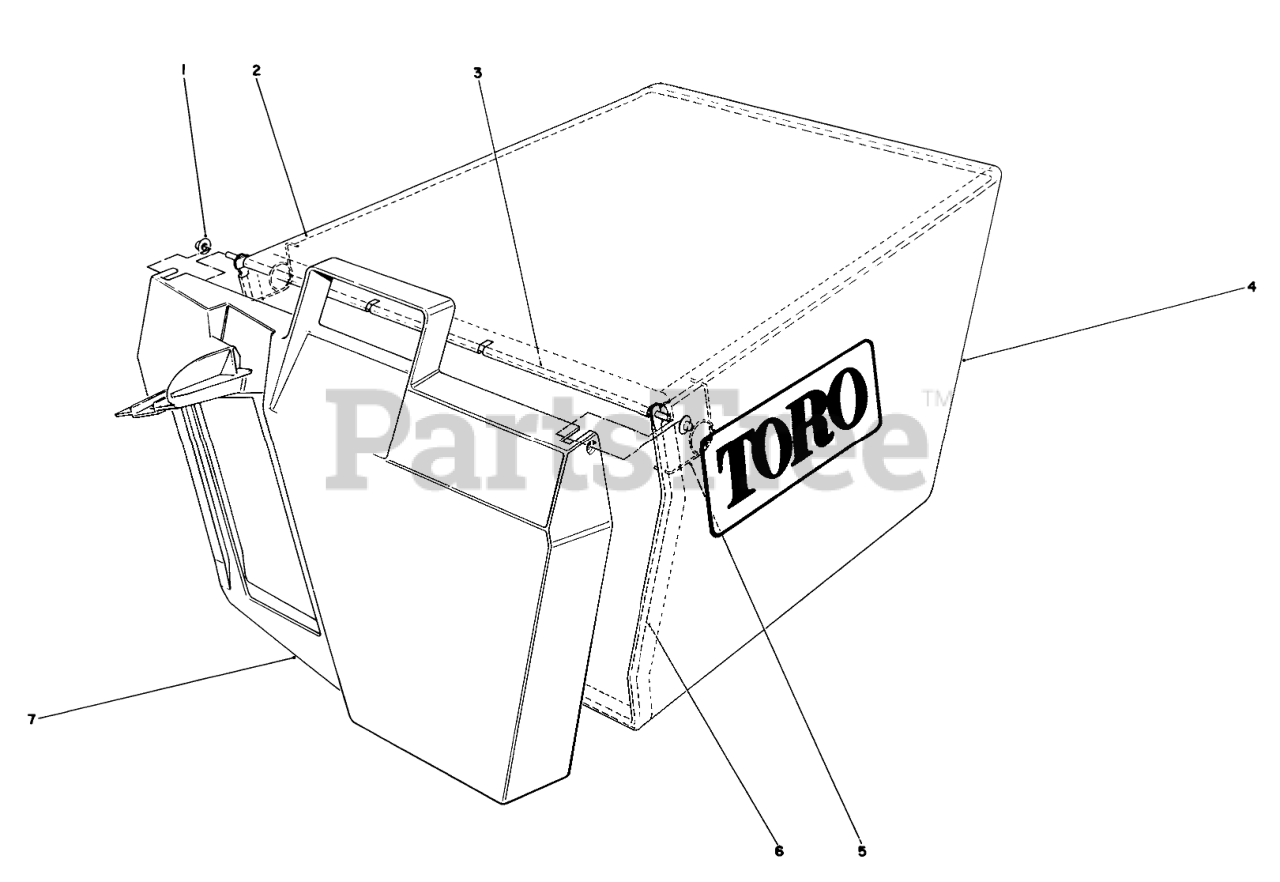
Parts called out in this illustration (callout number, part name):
1	NUT-PUSH
2	FRAME-BAG, UPPER
3	HINGE-DOOR, BAG
4	Bag
5	SPRING
6	BAG FRAME
7	BAG DOOR
